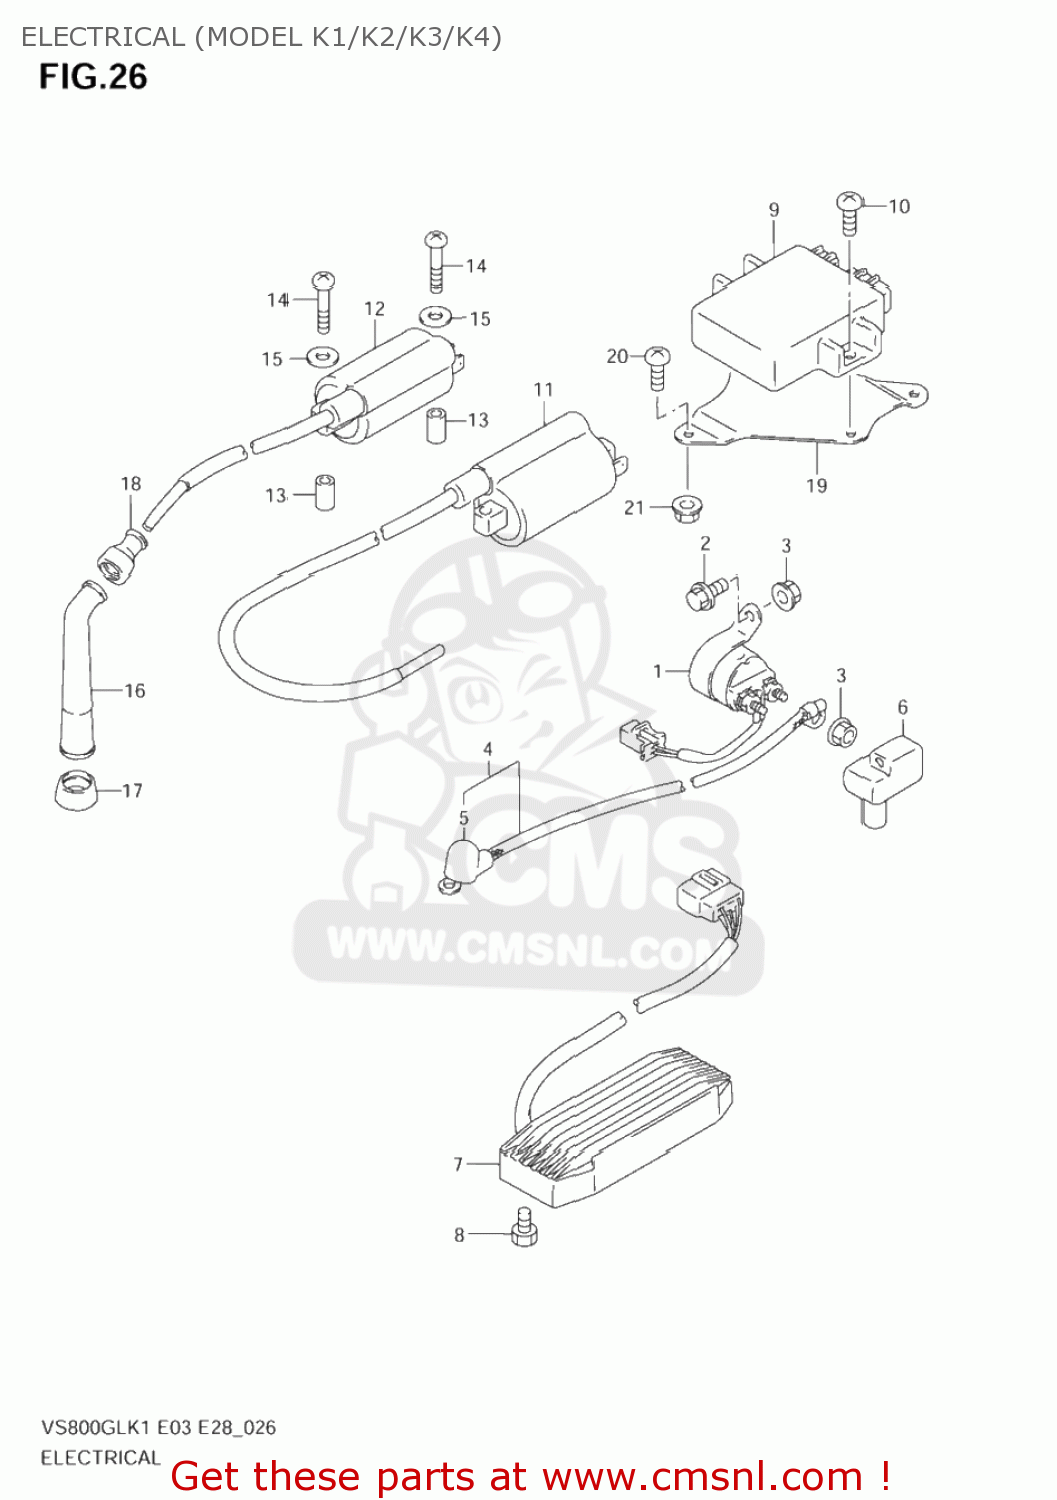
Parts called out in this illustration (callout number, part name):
1	RELAY ASSY,STARTING MOTOR
2	BOLT
3	NUT
4	WIRE,STARTER MOTOR LEAD
5	CAP,STARTER MOTOR LEAD
6	CAP,STARTER RELAY
7	RECTIFIER ASSY
8	BOLT
9	IGNITOR ASSY
10	SCREW 6X12
11	COIL ASSY,IGNITION
12	COIL ASSY,IGNITION
13	SPACER(6.4X10X19)
14	SCREW (5X38)
15	WASHER
16	CAP,SPARK PLUG
17	SEAL,SPARK PLUG CAP
18	SEAL,HIGH TENSION CORD
19	PLATE,IGNITOR FITING
20	BOLT
21	NUT
